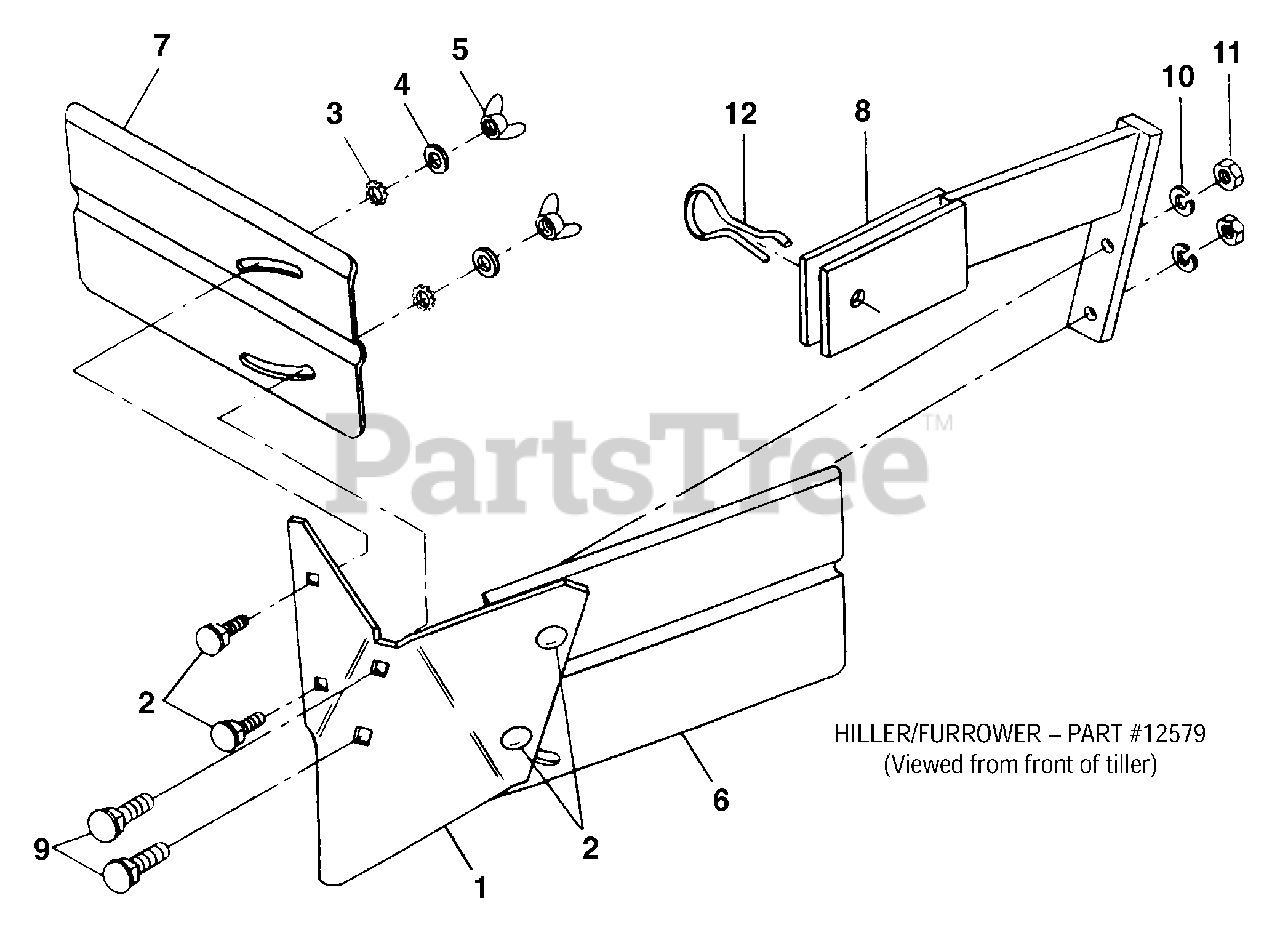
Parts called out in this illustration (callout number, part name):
1	Furrower-blade only
2	Carriage Bolt-5/16-18 x 3/4
3	Star Washer-external tooth, 5/16
4	Plain Washer-5/16 S.A.E
5	Wing Nut-5/16-18
6	Hiller Wing-left
7	Hiller Wing-right
8	Bracket-blade mounting
9	Carriage Bolt-blade mounting, 3/8-16 x 1-1/2
10	Lockwasher-3/8, plated
11	Nut-hex, 3/8-16, plated
12	Pin-clinch
